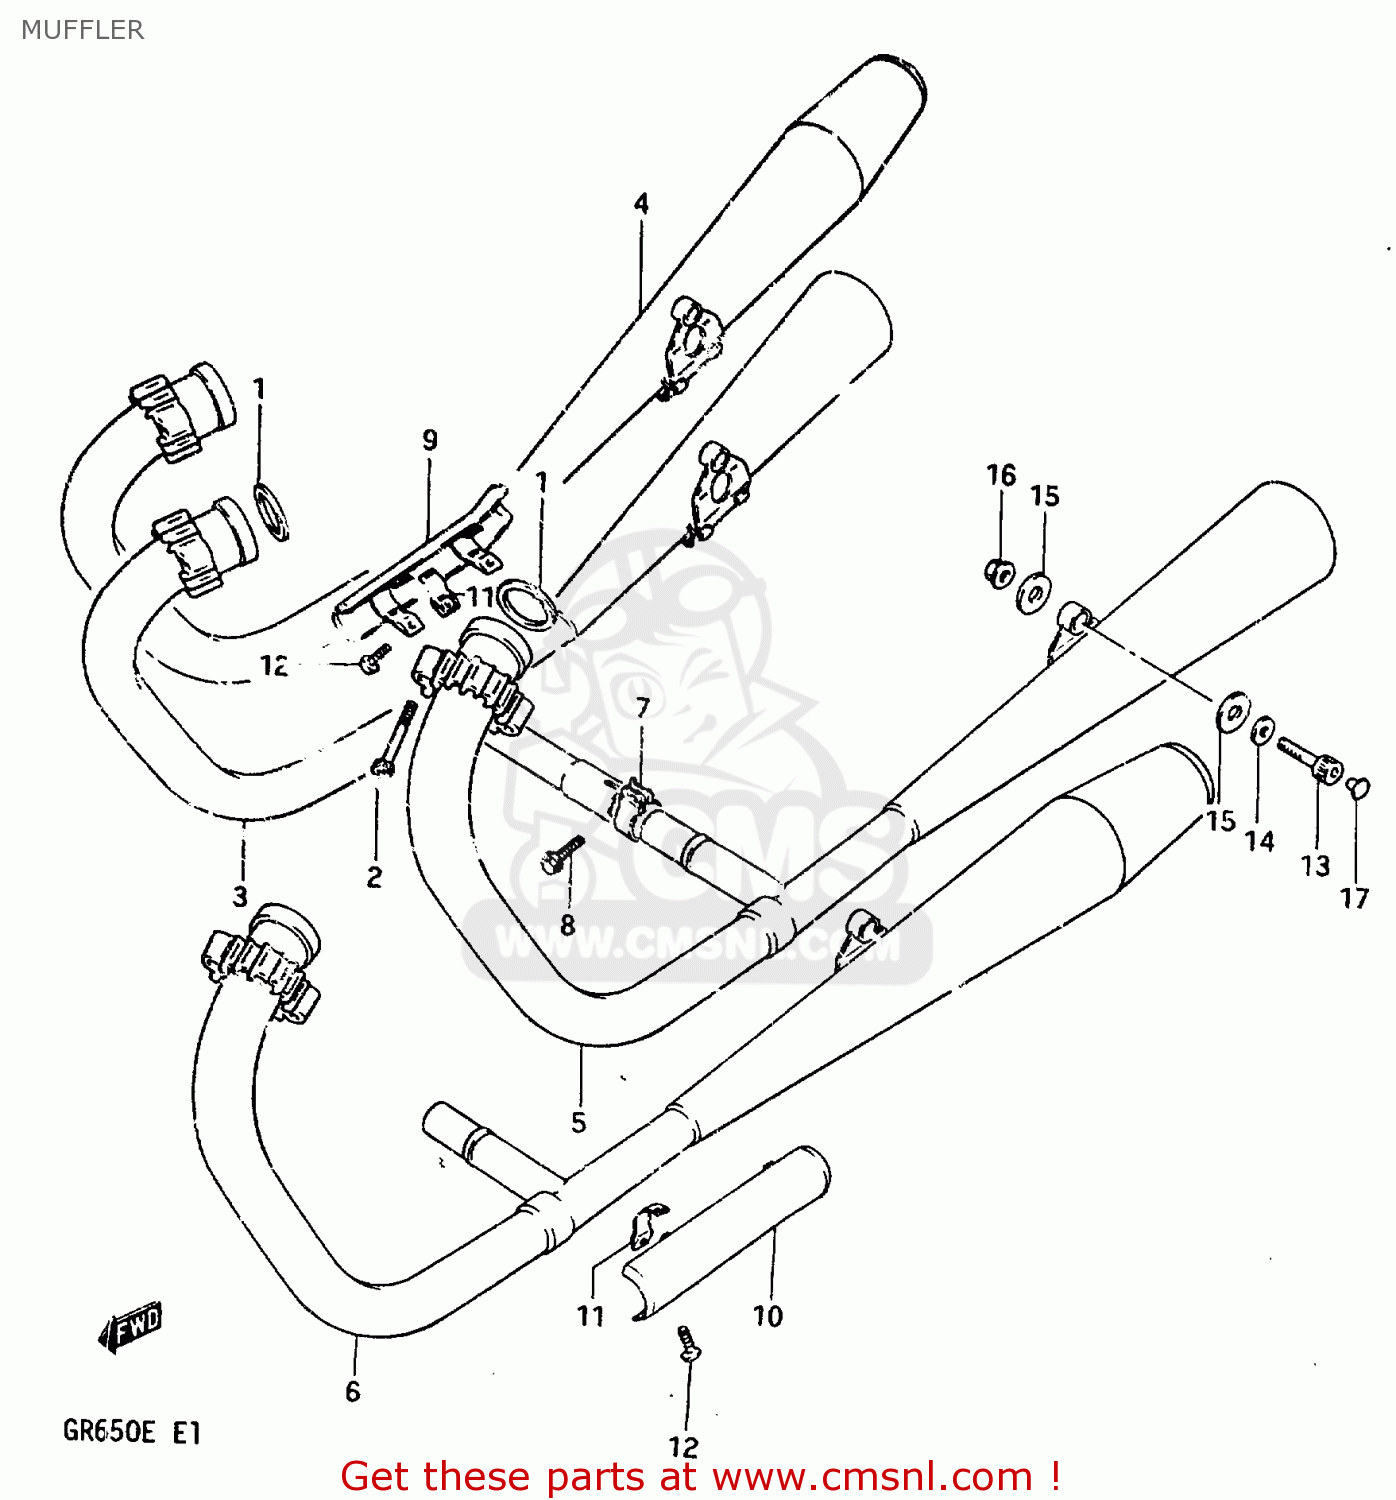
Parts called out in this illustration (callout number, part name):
1	GASKET,EXHAUST PIPE (NAS)
2	BOLT
3	MUFFLER ASSY,R
4	MUFFLER, RH
5	MUFFLER ASSY,L
6	MUFFLER, LH
7	CLAMP,EXHAUST
8	BOLT
9	COVER,MUFFLER,RIGHT
10	COVER,MUFFLER,LEFT
11	CLAMP,MUFFLER COVER
12	SCREW
13	BOLT
14	WASHER
15	WASHER(10.5X22X2.3)
16	NUT ,10MM
17	CAP
